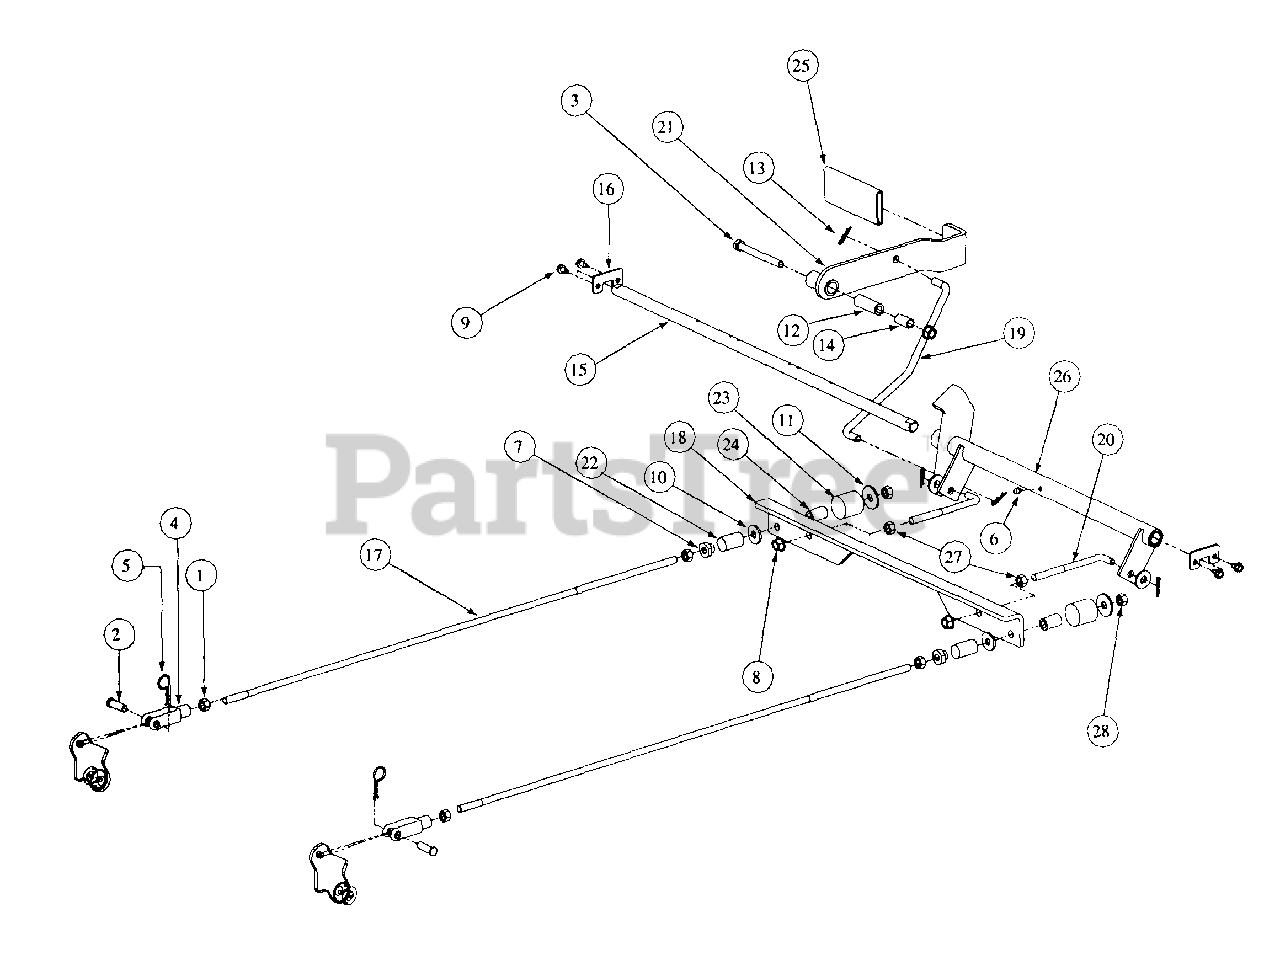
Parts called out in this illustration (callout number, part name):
1	Hex Nut, 3/8-16
2	Clevis Pin, 3/8 x 1, 1/8
3	HHCS, Standard, 3/8-16 x 3-1/2
4	Yoke, 3/8-16, Female
5	Hair Pin, 3/8"-1/2"
6	Grease Fitting, 1/4-28, 90°.
7	Shoulder Nut
8	Nut, Flange Lock, 3/8-16
9	Screw, TT, 1/4-20, .5, Hex Index Washer
10	Flat Washer, .406 ID, 1.0 OD, .105
11	Flat Washer, .411 x 1.25 x .100
12	Spacer, .39 ID x .63 OD x 1.75
13	Cotter Pin, INT .072 x 1.12
14	Spacer, .375 x .50 x 1.02
15	Mounting Shaft, Bellcrank
16	Holder Shaft, Park Brake
17	Rod Connector, 3/8 OD 5.75
18	Brake Bracket
19	Rod Brake,
20	Rod Connector, 3/8 OD x 33.
21	Weldment, Handle Brake
22	Brake Spring, Neutral
23	Brake Spring, Force
24	Brake Hose, Center
25	Grip, Park Brake
26	Weldment Hub, Brake Bearing
27	Jam Nut, 3/8-16
28	Lock Nut, Nylon Insert, 3/8-16
